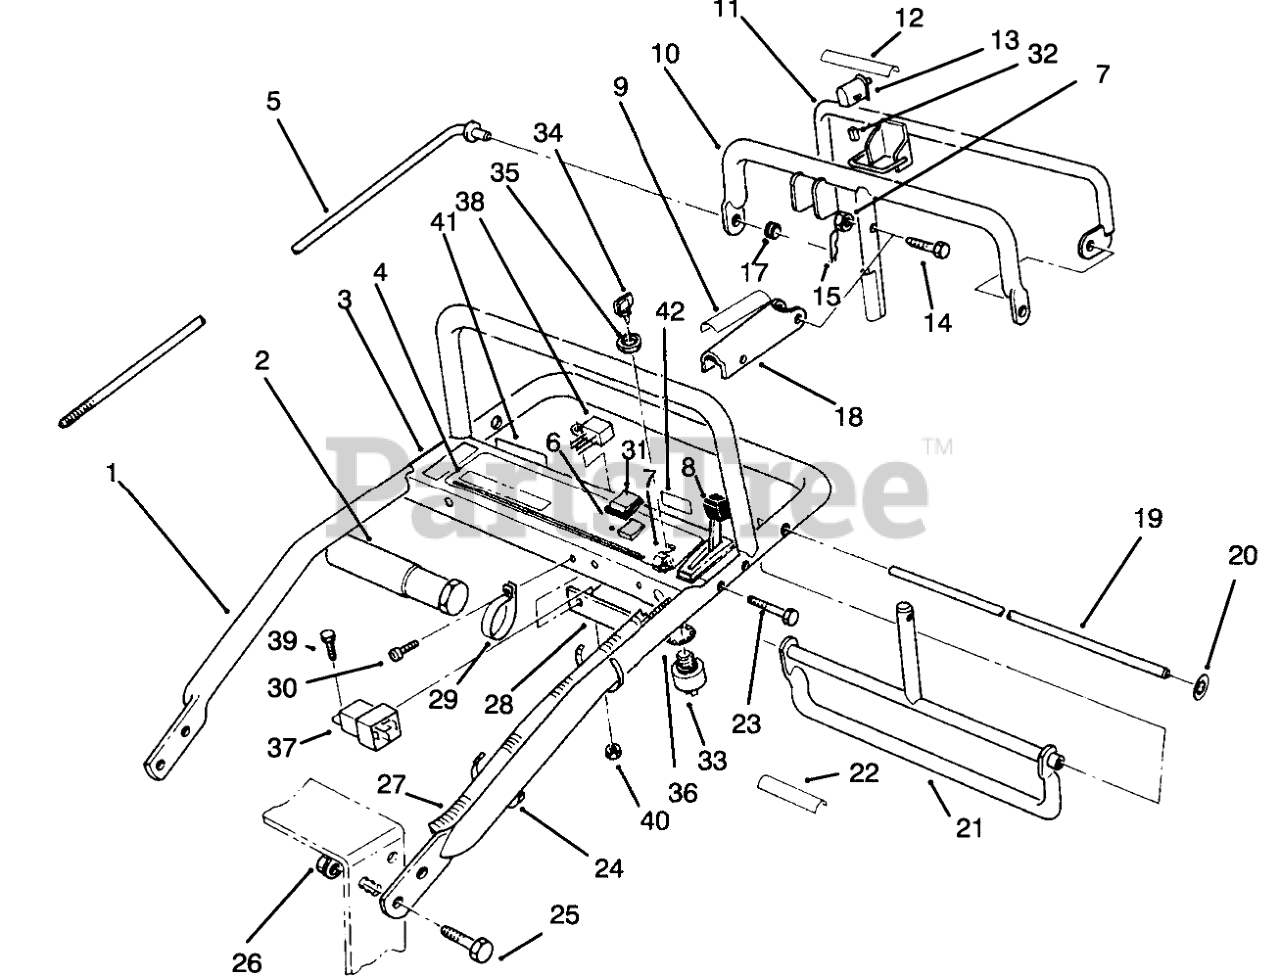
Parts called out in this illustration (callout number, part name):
1	Handle-Upper
2	TUBE-MANUAL
3	Panel-Control
4	DECAL-CONTROL PANEL
5	ROD-CONTROL
6	SWITCH
7	NUT-LOCK, NI
8	CONTROL-THROTTLE
9	DECAL-LEVER, PARKING
10	Bar
11	Bail
12	DECAL
13	SWITCH-BAIL
14	SCREW-SHH
15	PIN-COTTER
17	GROMMET-RUBBER
18	Lever-Parking Brake
19	PIVOT ROD
20	NUT-PUSH-ON, CIRCULAR
21	Control Pivot
22	DECAL
23	SCREW-SHH
24	TIE-CABLE
25	SCREW-HHF
26	NUT-HF
27	WIRE HARNESS
28	Panel-Bottom
29	CLAMP-R
30	SCREW-HWHTF
31	BOOT-SWITCH
32	CONNECTOR-BODY
33	Switch-On/Off (Incl. Ref. #34-36)
34	KEY-IGNITION
35	NUT-HH
36	WASHER-TOOTH, INTERNAL
37	RELAY
38	Module
39	SCREW-HH
40	NUT-LOCK, NI
41	DECAL/INSTRUMENT PANEL
42	DECAL-INSTRUCTION
